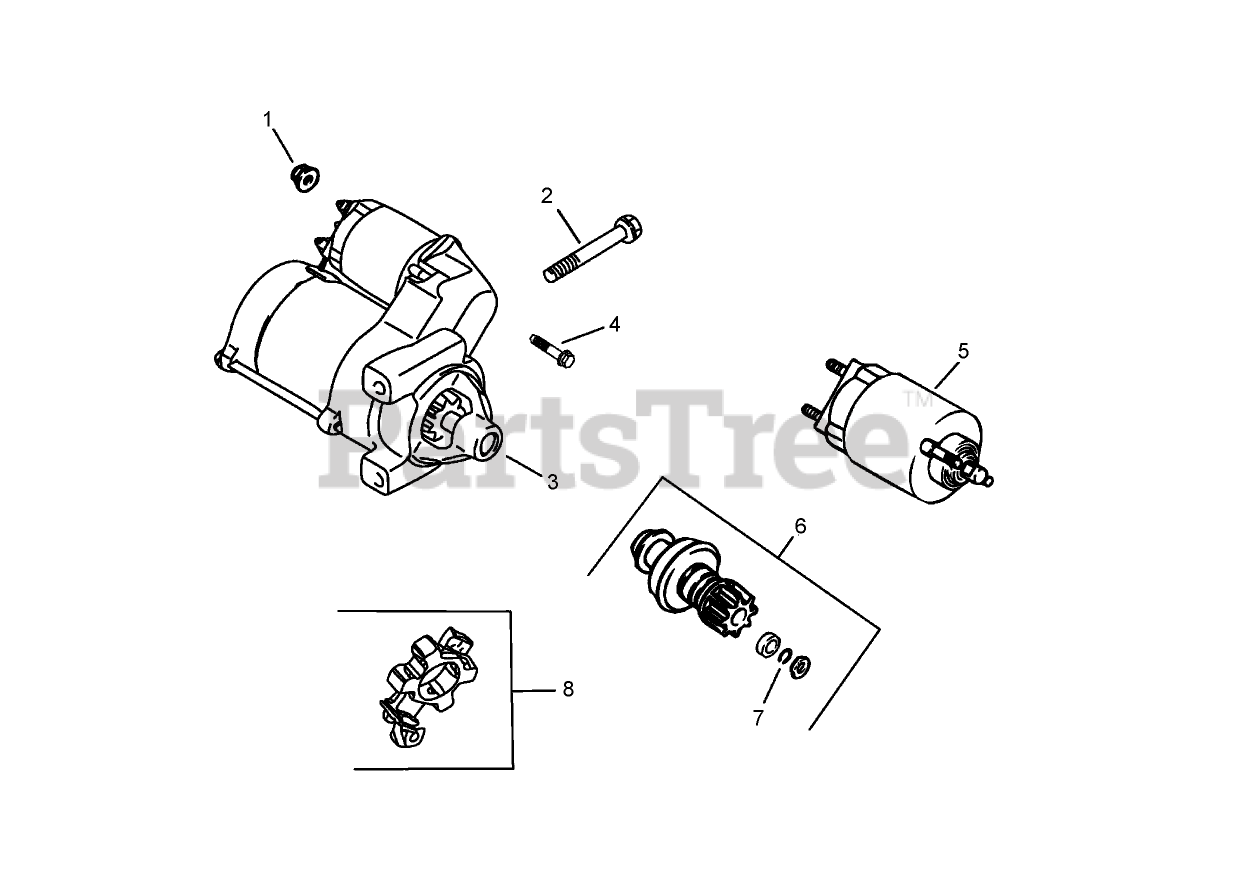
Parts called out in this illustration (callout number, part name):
1	NUT-FLANGE (M8X1.25)
2	SCREW-FLANGE (M8X1.25X80)
3	Starter ASM (Includes 4-8) (service starter and components according to starter brand and number)
4	SCREW-TORX HEAD, EXTERNAL
5	Solenoid Kit (Includes 4)
6	Pinion Drive Kit (Includes 7)
7	RING-RETAINING
8	BRUSH HOLDER KIT
